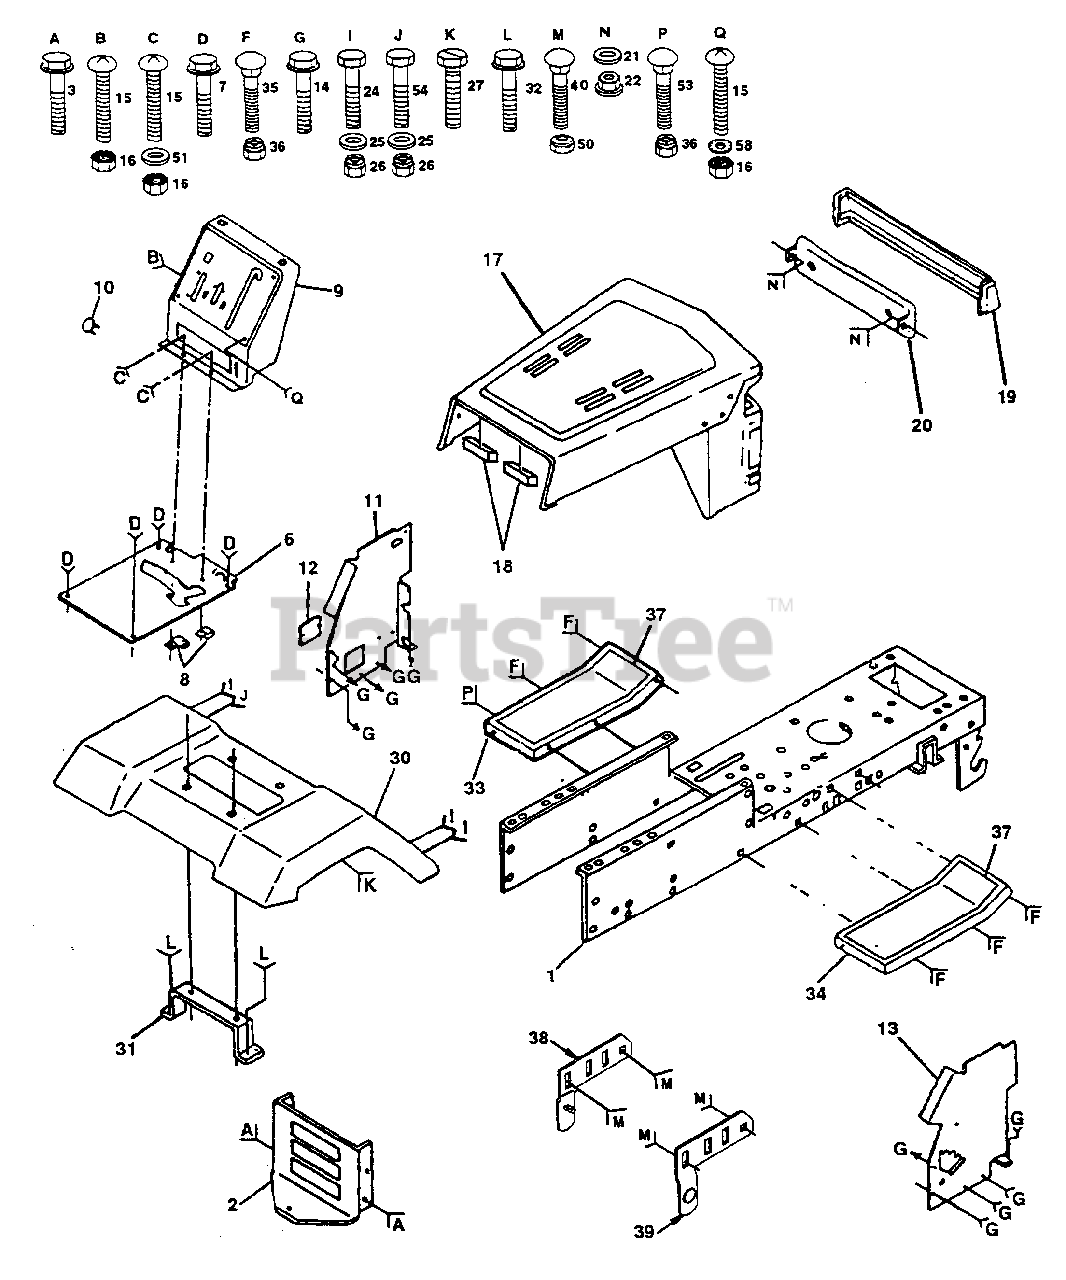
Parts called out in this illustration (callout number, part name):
1	Chassis Wldmt 12 Ga 38/42 W/pvt
2	Drawbar, Stretch
3	Screw Thdrol 3/8-16x3/4 Ty-tt
6	Saddle Slk 6sp LT Flat
7	Screw Thdrol 3/8-16x1/2 Ty-tt
8	Clip Line Fuel 13/32 Mtg Hole
9	Dash Slkscr 1-pc M W/i N/c Sym
10	Plug Button Blk 359 Dia Choke
11	Panel Dash LH
12	Cover Access Black Square
13	Panel Slkscr Dash RH Wld Notch
14	Screw Thdrol 3/8-16x1/2 Ty-tt
15	Screw Mach TRHD 5/16-18uncx3/4
16	Nut Keps 5/16-18 Unc
17	Hood Asm Pnt Weld
19	Lens Headlight Bar Clear
21	Washer 9/32 x 3/4 x 16 Ga.
22	Nut Pal
24	Bolt Fin Hex 3/8-16unc X 3/4
25	Washer 13/32 X 13/16 X 12 Ga
26	Nut Crownlock 3/8-16 Unc
27	Screw Thdrol 3/8-16x1/2 Ty-tt
31	Bracket Fender Repl 109873x
32	Screw Thdrol
33	Footrest Pnt LH (Husq Gray)
34	Footrest Pnt RH (Husq Gray)
35	Bolt Rdhd Sht Sqnk 3/8-16 X3/4
36	Nut Crownlock 3/8-16 Unc
37	Pad Footrest Ribbed
38	Bracket Asm Pvt42 LH MWR Rear
39	Bracket Asm Pvt42 RH MWR Rear
40	Bolt Rdhd Sqnk 3/8-16unc X1
50	Nut Lock Hex W/wsh 3/8-16unc
51	Washer 13/32 X 3/4 X 16 Ga
53	Bolt Rdhd Sqnk 3/8-16unc X 1
54	Bolt Fin Hex 3/8-16unc X 7/8
58	Washer Lock Ext. Tooth 3/8
